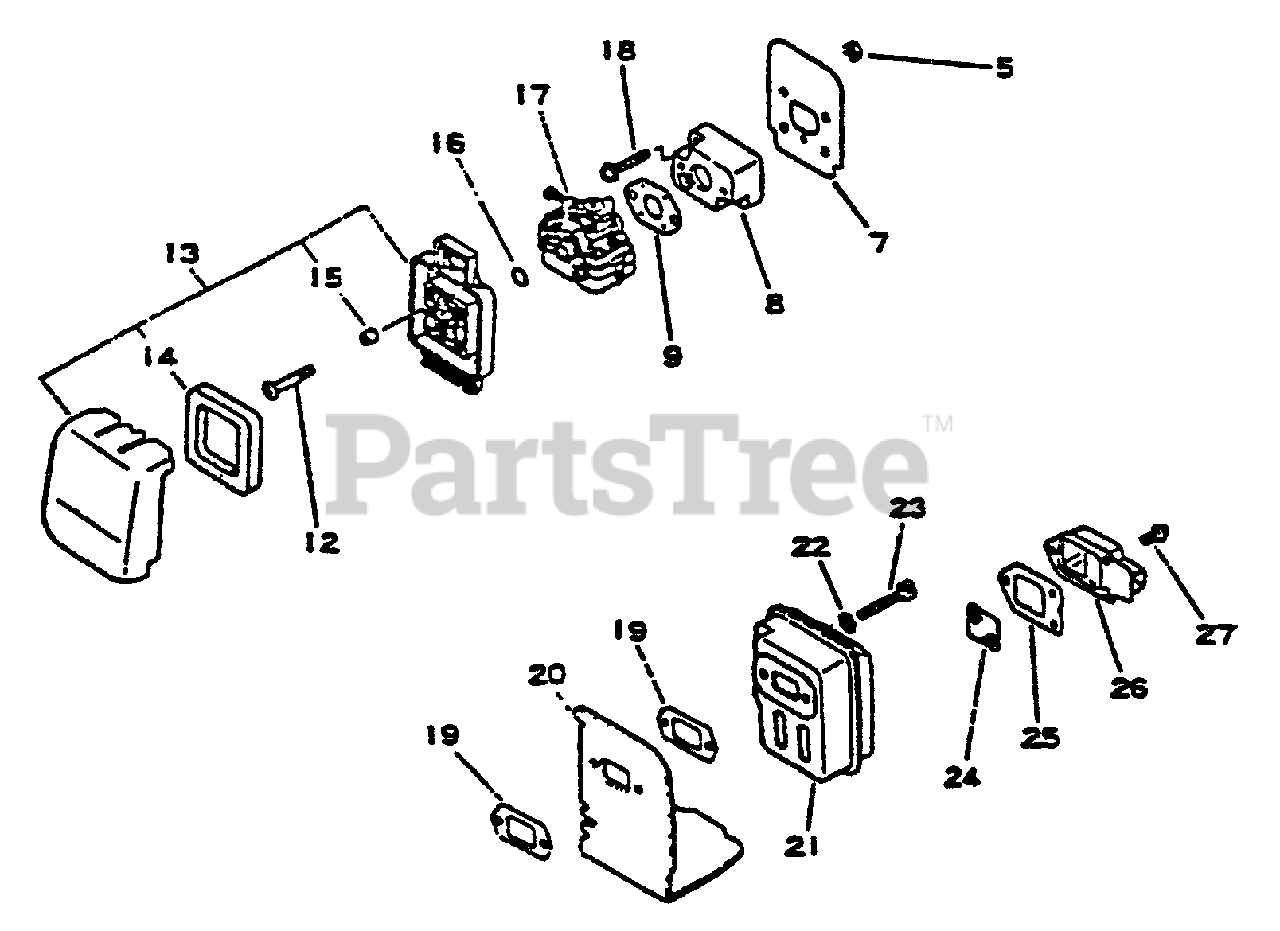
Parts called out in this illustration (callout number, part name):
7	SHIELD, INTAKE
8	INSULATOR, INTAKE
9	GASKET, INTAKE
12	SCREW - 5X64
13	AIR CLEANER ASSY
14	FILTER, AIR
15	SLEEVE
16	O-RING - 15
17	CARBURETOR WYL-6
17	CARBURETOR WYL-1
18	SCREW - 5X22
19	GASKET, EXHAUST
20	COVER, EXHAUST
21	MUFFLER
22	WASHER - 5
23	SCREW - 5X55
24	SCREEN, SPARK ARRESTOR
25	GASKET, EXHAUST
26	GUIDE, EXHAUST - OUTER
27	SCREW - 4X10
